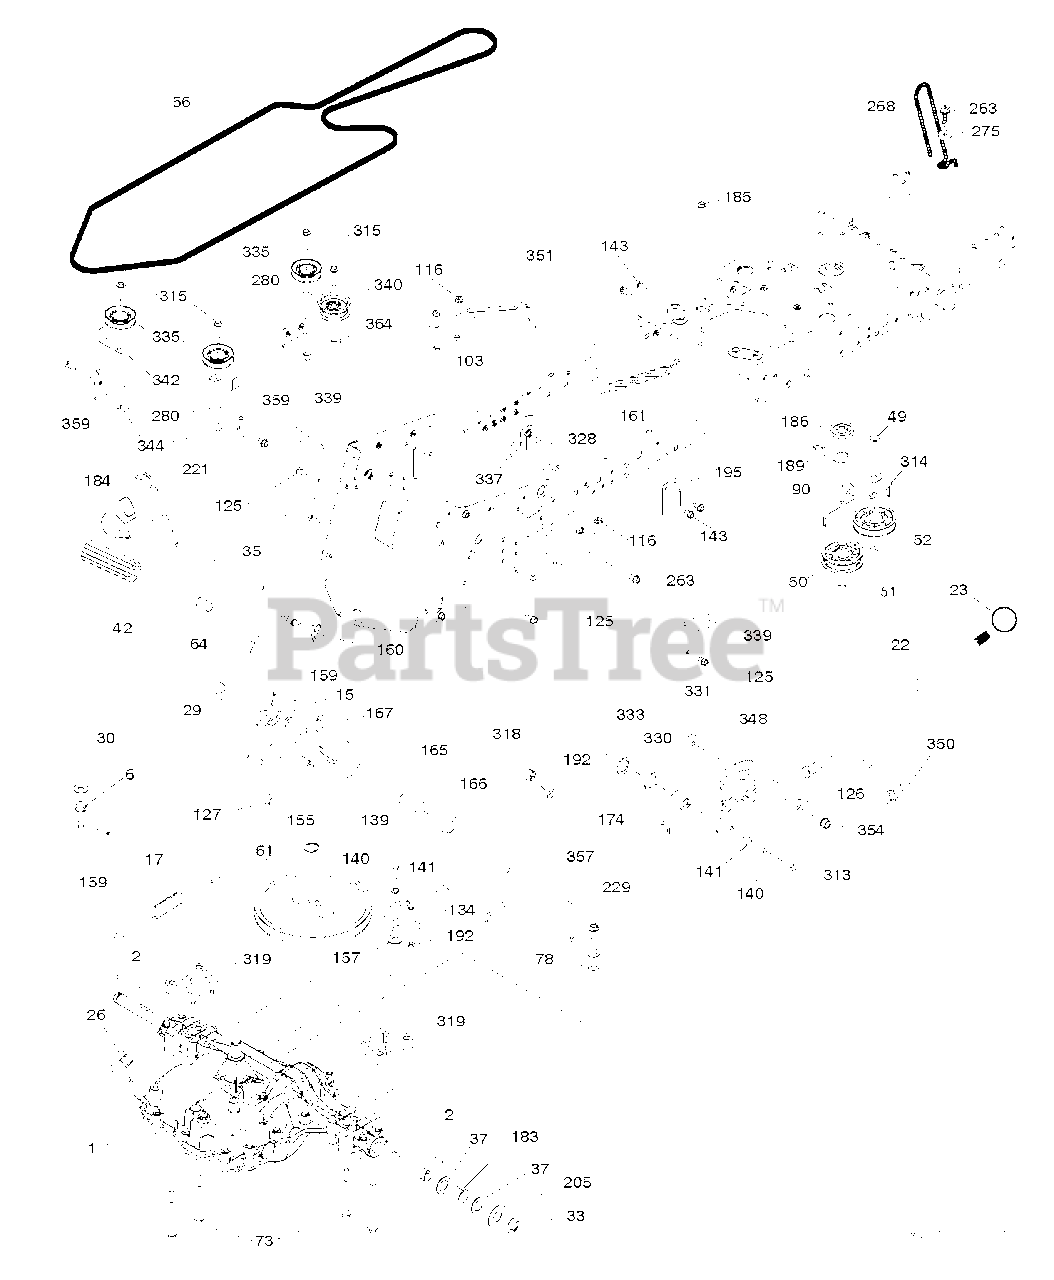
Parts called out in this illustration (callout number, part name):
2	SQUARE KEY
6	MANDREL ASS'Y
23	KNOB.DUCKHEAD.1/2
26	SPRING,BRAKE RETURN
33	E-RING LT
35	ROD, BRAKE, PARK
42	PEDAL COVER T
49	BOLT
50	IDLER.FLAT.910.OFFSET
51	NUT LOCK FLG 3/8-16 UNC
52	IDLER.V-GROOVE.910.OFFSET
64	SHAFT.ASM.PEDAL.BRAKE.
78	WASHER
103	JAM NUT TI
116	NUT LOCK HEX FLANGE 5/16-18
125	SCREW
126	WASHER.SRRTD.5/16
127	LINK.CLUTCH.GROUND.DRIVE
134	ARM SHIFT
139	BOLT 1/4-28X3/4
140	LOCKWASHER
141	WASHER LT
155	RETAINING RING LT
157	WASH-SHFT PLT LT
159	COTTER PIN
160	RETAINER CLIP
161	SPRING, RETURN LT
165	BUSHING.SHAFT.BRAKE.HAND
166	NUT.PUSH.625
167	LATCH.BRAKE.SPRING
174	NUT.PUSH.500.2006
183	SPACER AXLE
184	HANDLE.PARKING.BRK.PRED.LT.RED
186	SPACER.RETAINER
192	NUT LOCK CENTER 1/4 -28 FNTHD
221	RETAINER.SPRING.CLIP.H
229	SCREW 5/16-18X1
263	SCREW, 3/8-16X3/4
275	WASHER
315	BOLT.5/16-18X1.25
330	WASHER.NYL.7/8IDX.105"HYD CR
335	PULLEY.V-IDLER.
359	SCREW LT.3/8-46X5/8
